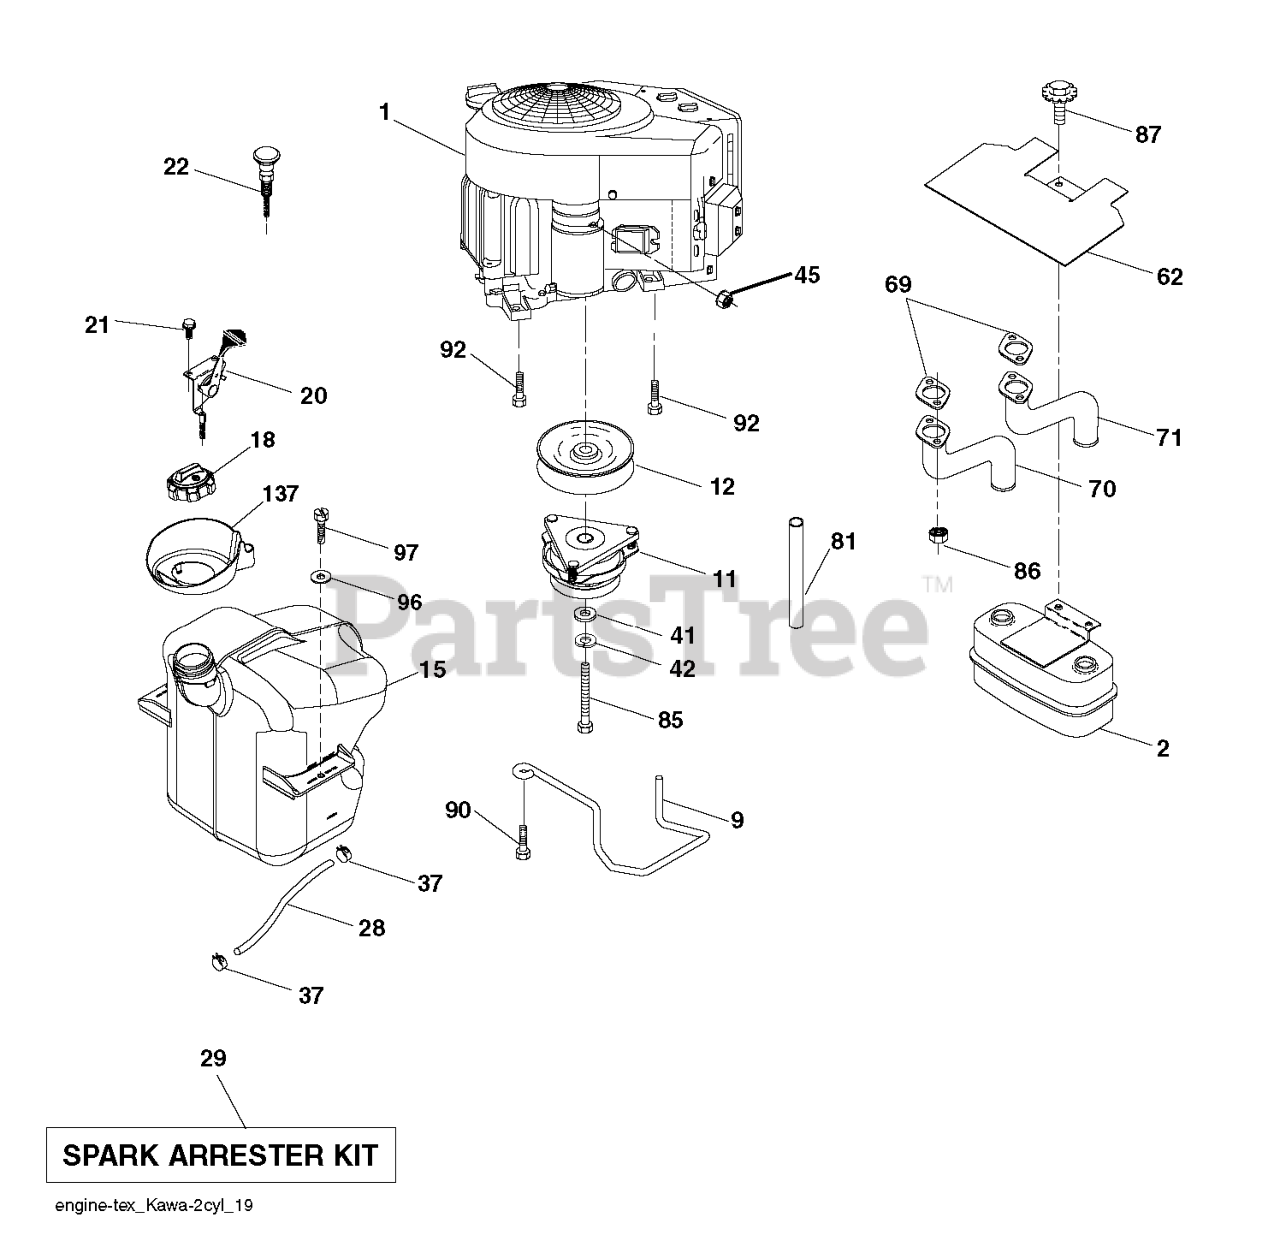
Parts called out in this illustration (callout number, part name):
2	MUFFLER.ASM.TWN.EXTNDED.DFLCTR
9	KEEPER.BELT.ENGINE.4.2
11	CLUTCH.ELECTRIC.LT.48"*
12	PULLEY.ENGINE.TUFFTORQ
15	FUEL TANK TANK. ASSEMBLY. EXTE
18	CAP.ASM.FUEL.2.25"TOP.TURN
20	CONTROL.THROTTLE.COBRA.BLACK
21	SCREW.#10 X 0.750.BOS
22	CONTROL, CHOKE
28	LINE.FUEL.20
29	KIT.SPARK ARRESTOR 794945 B&S
37	HOSE CLAMP
42	LOCKWASHER
45	NUT
62	SHIELD.HEAT.MUFFLER
70	TUBE.EXHAUST.LH.FR961/FR730
71	TUBE.EXHAUST.RH.FR961/FR730
81	TUBE, DRAIN OIL ASM.
85	BOLT HEX 7/16-20X4-1/4"
86	NUT.HEX.FLANGE.TOPLOCK
87	BOLT.5/16-18UNCX3/4 W/SEMS.BLK
90	SCREW 3/8-16X1
92	SCREW 3/8-16X1
96	WASHER
